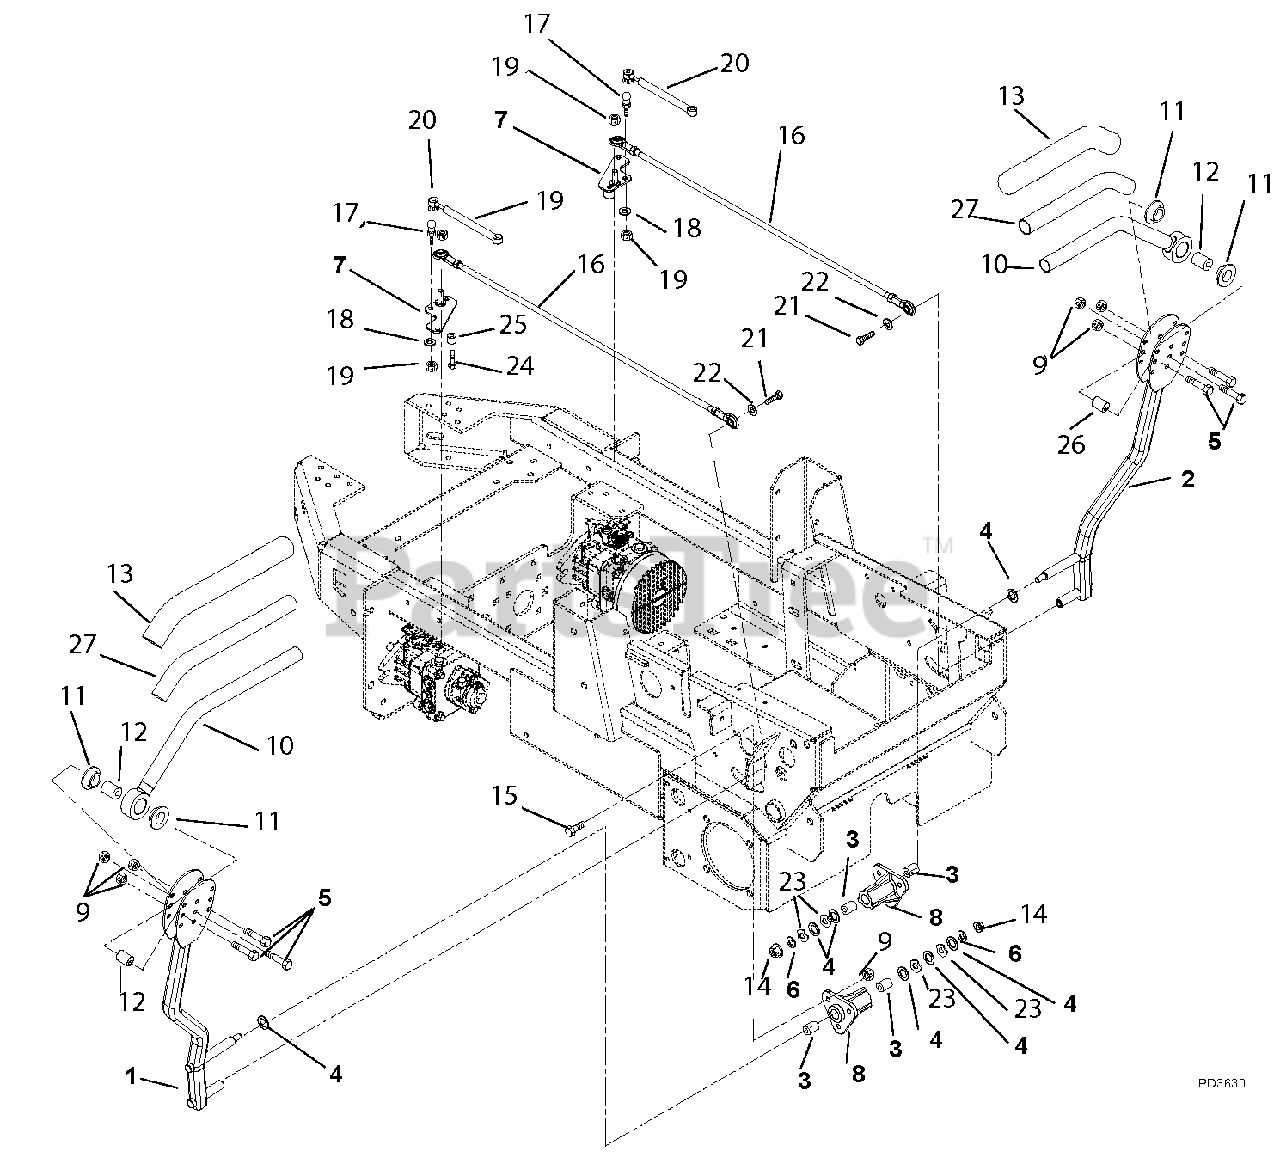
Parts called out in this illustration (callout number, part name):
1	Weldment, Bent Steering Arm - Right Hand
2	Weldment, Bent Steering Arm - Left Hand
3	Bushing .625 x .75 x .50
4	Washer, Flat Steel .630 x 1.005 x .062
5	Bolt, Hex .31-18 x 1.75 Grade 5
6	Washer, Flat Steel .438 x 1.00 x .083
7	Weldment, Damper, Steering
8	Housing, Bushing
9	Nut, Nyloc Flange .31-18
10	Handle, Left Hand
11	Bushing, Flange Nylon .762 x 1.48 x .44
13	Grip, Handlebar
14	Nut, Nyloc Flange .38-16
15	Bolt, Round Head Square Neck .31-18 x 1.00 Grade 5
16	Assembly, Steering Rod .38ROD x 30.43LG
17	Stud, Ball
18	Washer, Locking .31 x .078 Regular
19	Nut, .31-18 Nyloc Flange
20	Damper, Control
21	Bolt, Hex .38-16 x 1.00 EP30
22	Washer, Flat Steel .406 x .812 x .065
23	Wave Washer .640 x .875 x .125
24	Bolt, Hex .31-18 x 1.25 Grade 5
25	Spacer .318 x .430 x .375
26	Bushing, Eccentric .31 x .75 x .97
27	Tube, .88 ID x 1.00 OD x 10.75
